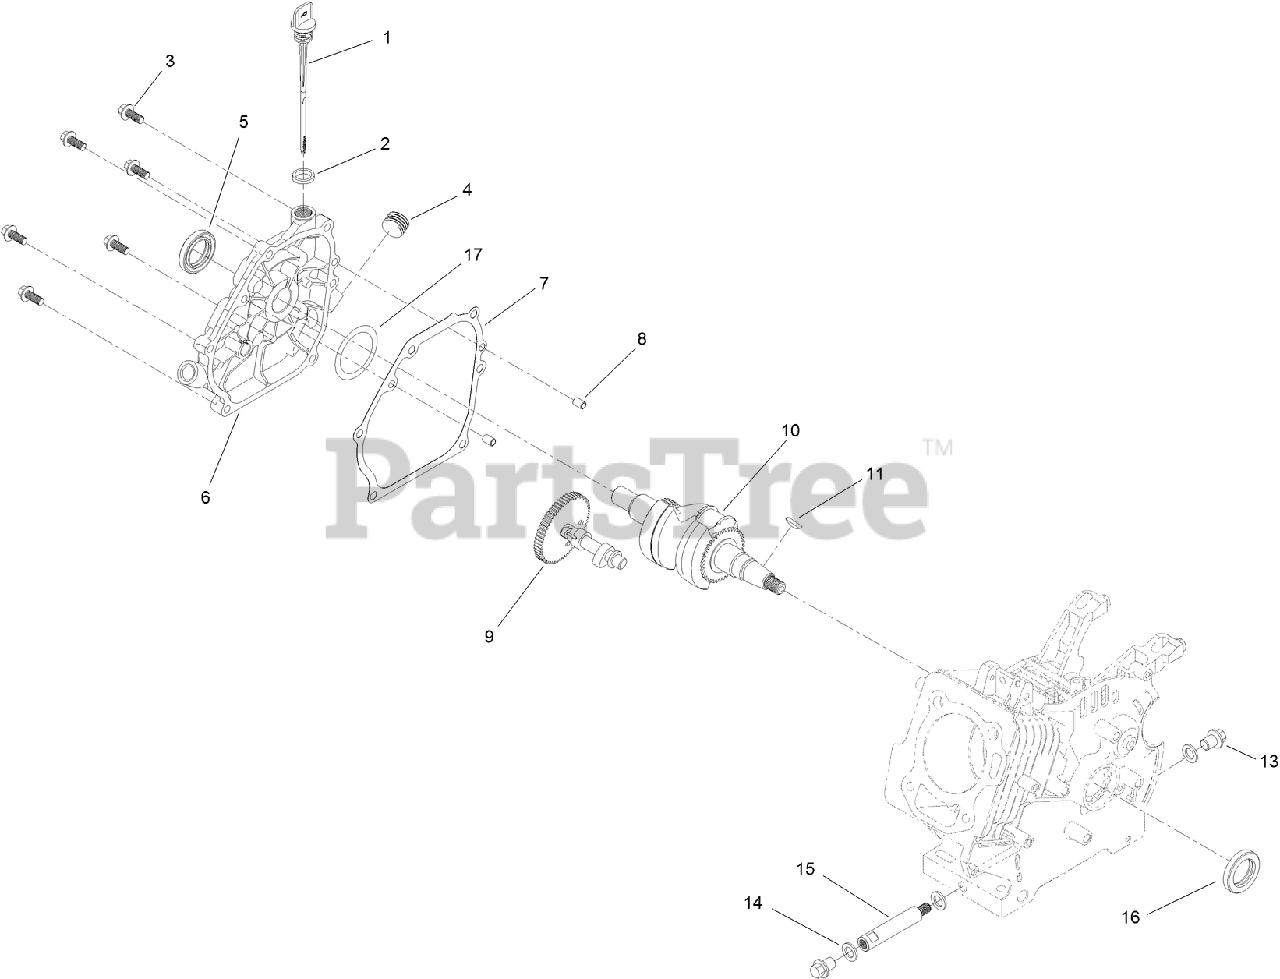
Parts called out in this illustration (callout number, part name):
1	DIPSTICK-OIL
2	GASKET-DIPSTICK, RUBBER
3	SCREW-HHF
4	Plug-Drain
5	SEAL-OIL
6	COVER-CRANKCASE
7	GASKET-COVER, CRANKCASE
8	PIN-DOWEL
9	CAMSHAFT ASM
10	CRANKSHAFT
11	KEY-WOODRUFF
13	SCREW-HHF
14	WASHER-PLAIN
15	TUBE-DRAIN, OIL
16	SEAL-OIL
17	WASHER-THRUST
